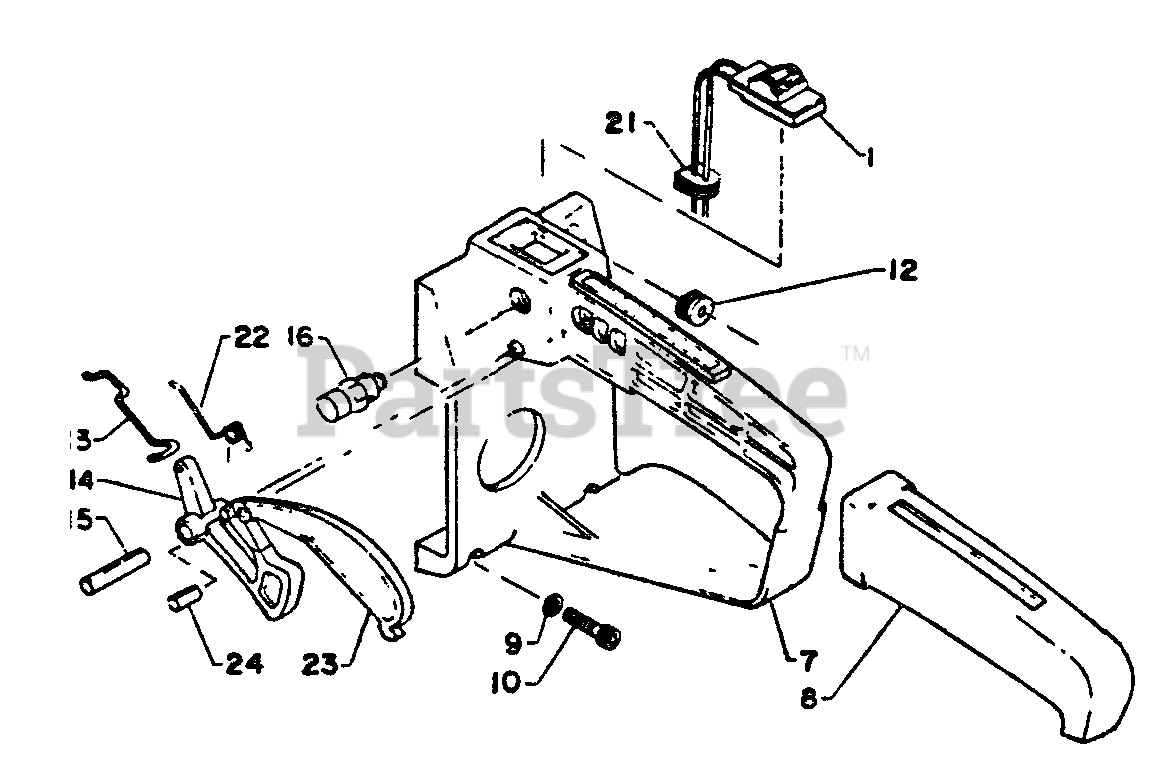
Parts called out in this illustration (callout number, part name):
1	IGNITION SWITCH ASSY
7	HANDLE - RIGHT
8	COVER, HANDLE
9	WASHER - 4
10	SCREW - 4X18
13	ROD, THROTTLE
14	TRIGGER, THROTTLE
15	PIN - SPRING -- 5X25
16	LATCH, THROTTLE
23	LOCKOUT, THROTTLE
24	PIN - SPRING -- 4X10
